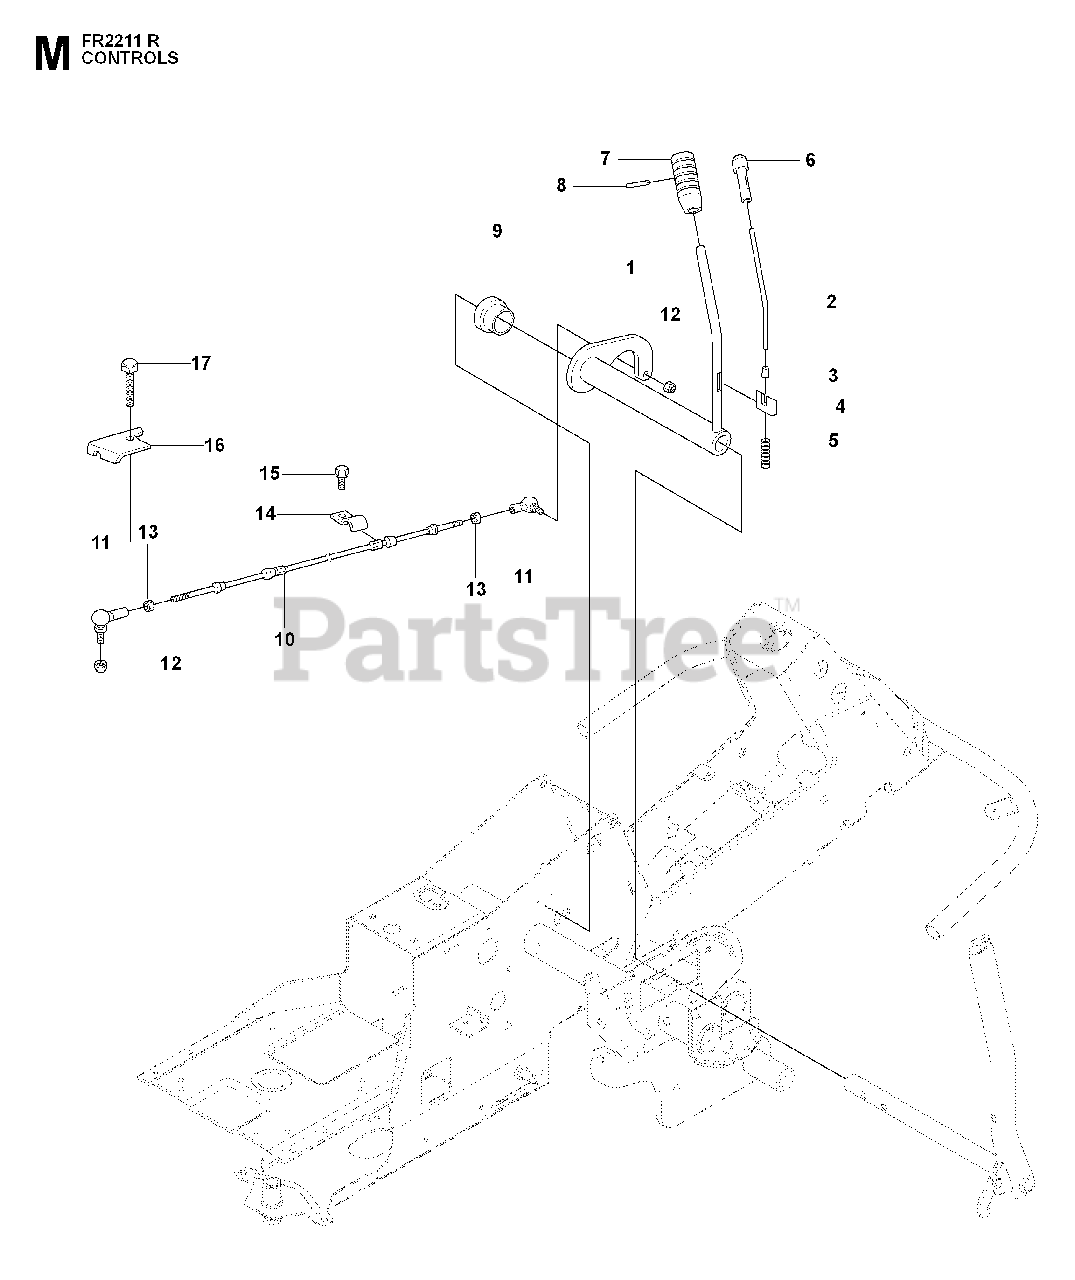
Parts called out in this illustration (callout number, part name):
3	END PIECE
8	SPRING PIN 3X24
9	BUSH
10	%ROD
11	CONNECTOR
12	LOCKNUT M5
